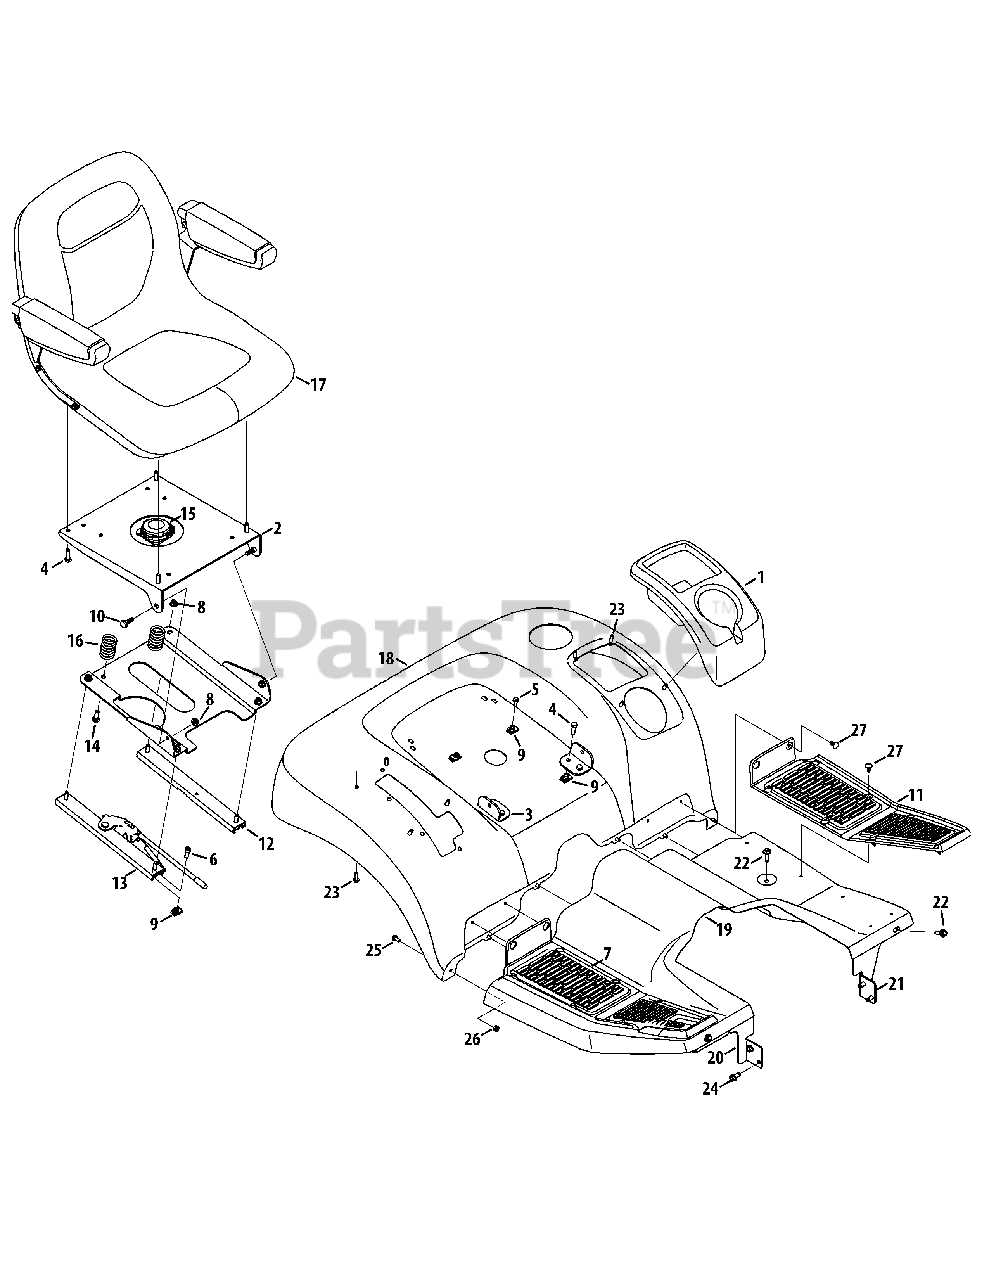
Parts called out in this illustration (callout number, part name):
1	LH Cup/Compartment Cover
2	Seat Mount Plate
3	Suspension Seat Front Pivot Bracket
4	Hex Screw, 5/16-18 x 1.00
5	Hex Flange Screw, 5/16-18
6	Socket Screw, 5/16-18 x .750
7	RH Floor Pad
8	Flange Lock Nut, 5/16-18
9	U-Nut, 5/16-18
10	Shoulder Screw, 5/16-18 x .437 x .268
11	LH Floor Pad
12	Seat Track w/o Latch
13	Seat Track w/ Latch
14	Carriage Screw, 5/16-18 x 1.00
15	Seat Switch, 1/4
16	Compression Spring
18	Fender
19	Running Board
20	RH Running Board Bracket
21	LH Running Board Bracket
22	Hex Washer Screw, 5/16-18 x 1.000
23	Hex Washer Screw, 1/4-15 x .750
24	Hex Washer Screw, 5/16-18 x .750
25	Hex Screw, 1/4-20 x .50
26	Hex Lock Nut, 1/4-20
27	Ratchet Clip, .250
